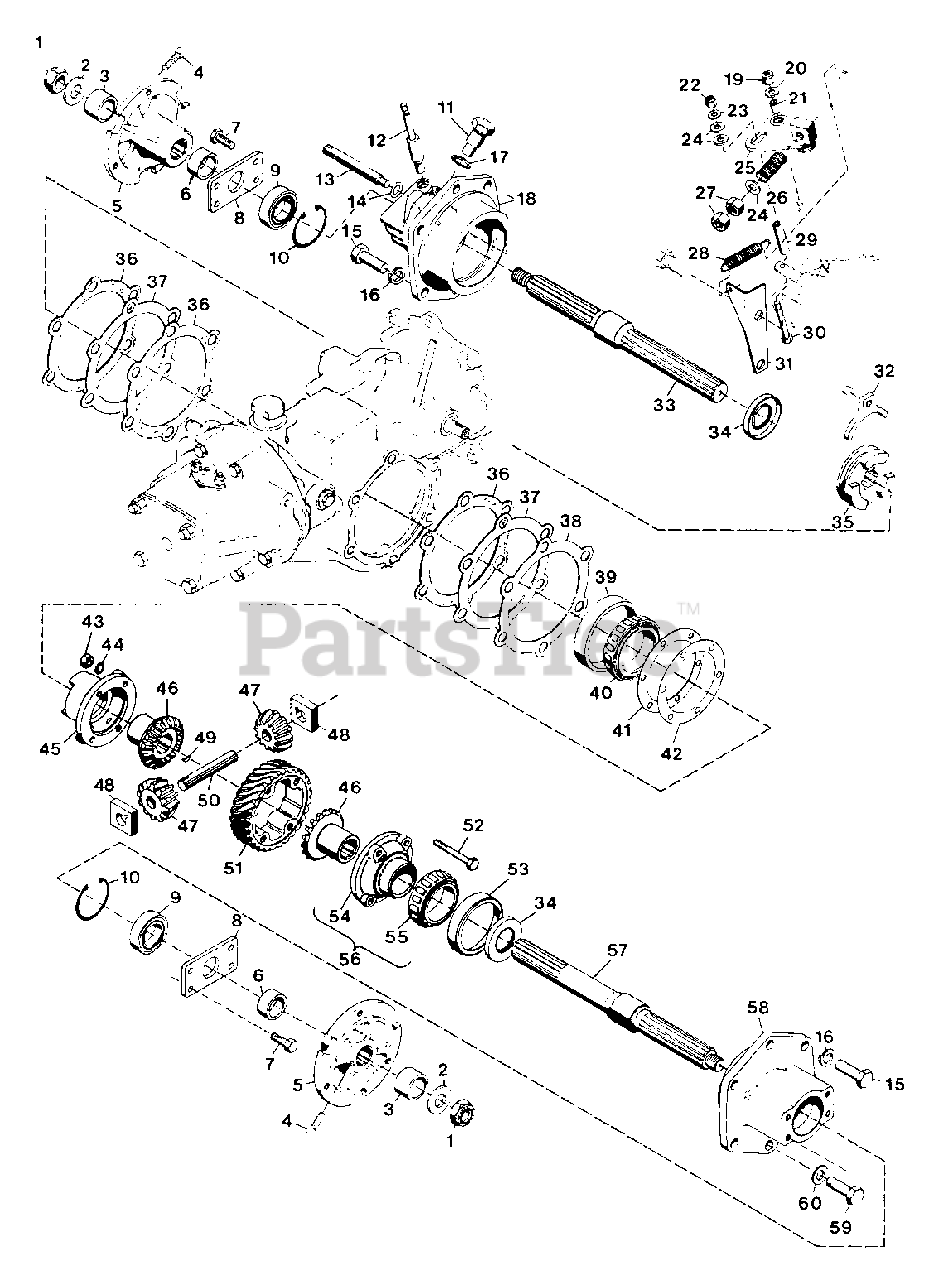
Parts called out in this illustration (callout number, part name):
1	Nut, Hex 3/4-10 Light Thin
2	Washer, Flat .812x1.469x.134
3	Spacer
4	Screw, Set 7/16-14x1.00 SQHCP
5	Hub, Wheel
6	Spacer
7	Bolt, Hex 3/8-16x.750
8	Plate, End
9	Bearing, Ball 1.000x2.000x.562
10	Ring, Retaining 2.000 Bore
11	Bolt, Stationary Clutch
12	Pivot, Stationary
13	Pin, Clutch Sliding
14	O-Ring, .438x.625x.094
15	Bolt, Hex 1/2-13x1
16	Washer, Lock 1/2 Reg.
17	Washer, Oil Strainer Nut
18	Housing, Axle 2-Speed
19	Nut, Lock 5/16-18
20	Washer, Flat .344x.688x.065
21	Bushing, Nylon .375x.503x.875
22	Nut, Lock 1/4-20
23	Washer, Flat .281x.625x.065
24	Washer, Flat .406x.812x.065
25	Weldment, Arm Shifter
26	Spring, Compression 2x.72x15.5
27	Nut, Jam 3/8-24 Hex
28	Spring, Extension 2.50x.62
29	Bushing
30	Bolt, 1/4-20x2.25 Gr. 8 PHd
31	Bracket, Spring 2-Speed
32	Yoke, Shifting
33	Axle, Straight Differential Lock
34	Seal, Oil 1.188x2.000x.250
35	Clutch, Sliding Differential Lock
36	Gasket, Axle Housing
37	Shim, Axle Housing .020
38	Shim, Axle Housing .005
39	Cup, Roller Bearing
40	Cone, Roller Bearing
41	Shim, Clutch Worm Gear .020
42	Shim, Clutch Worm Gear .005
43	Nut, Hex 5/16-24
44	Washer, Lock 5/16 Int. Tooth
45	Housing, Differential Lock
46	Gear, Differential Bevel
47	Gear, Spider Bevel
48	Block, Drive
49	Key, Woodruff .125x.375 Hard
50	Pin, Spider Pinion
51	Gear, 4 Lead Worm
51	Gear, 6 Lead Worm
52	Bolt, Hex 5/16-24x2.75
53	Cup, Roller Bearing
54	Housing, Differential
55	Cone, Roller Bearing
56	Assembly, Differential Housing
57	Axle, Straight
58	Housing, Axle
59	Bolt, Hex 1/2-13x1 Nylon Insert
60	Seal, Oil Drain
NS	Cone, Roller Bearing
NS	Weldment, 6-Lead Worm
NS	Welded Worm Shaft Asm- 6 Lead
NS	Weldment, 4-Lead Worm
NS	Welded Worm Shaft Asm- 4 Lead
NS	Decal, Model 5200
NS	Decal, Differential Lock
